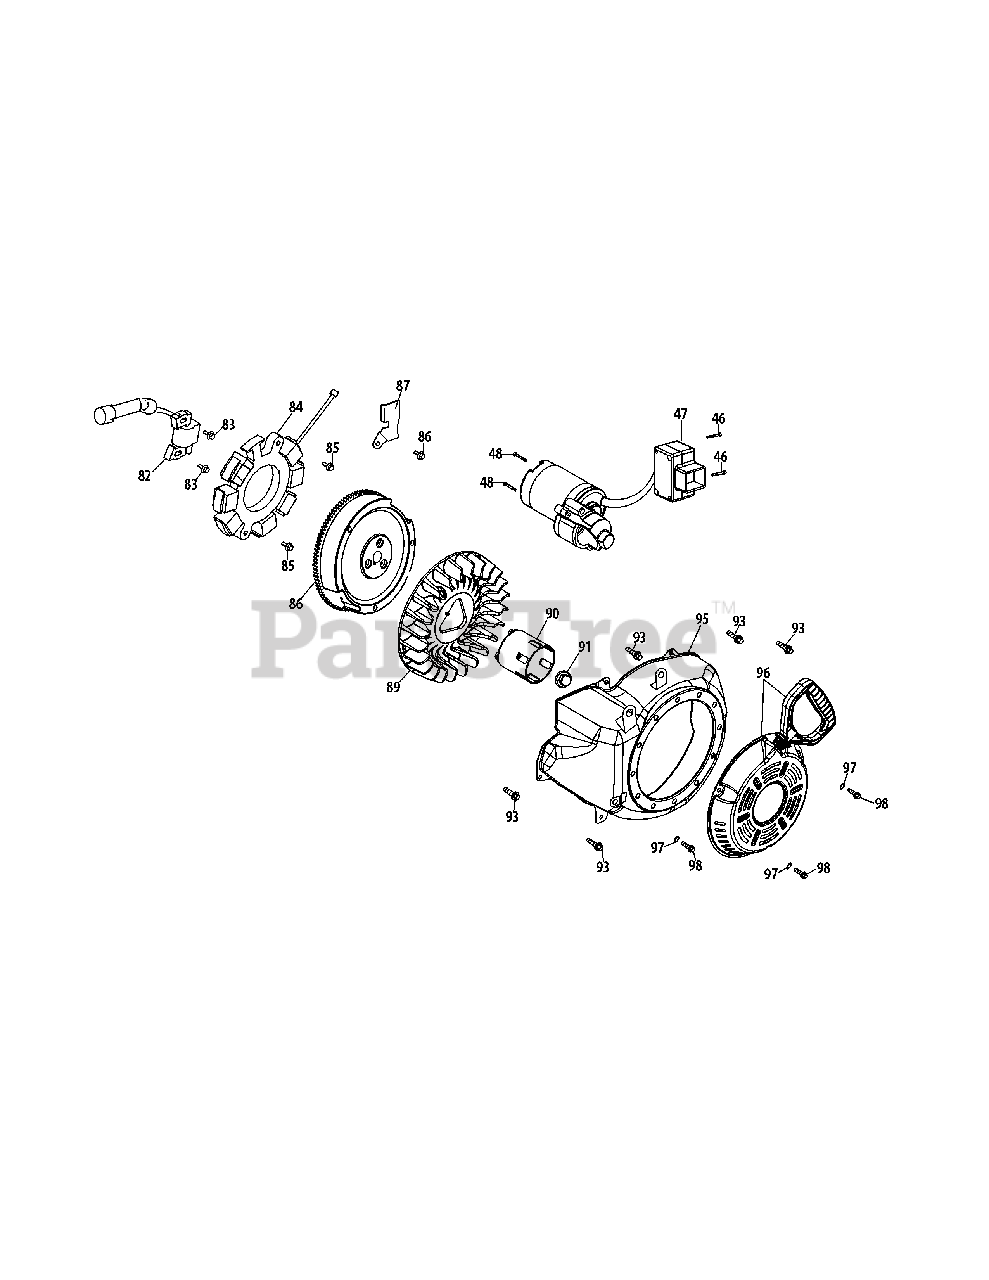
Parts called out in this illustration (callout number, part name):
47	Electric Starter
82	Ignition Coil Assembly
83	Ignition Coil Bolt
84	Coil Assy. Charge
87	Alternator Wire Clamp Brkt
90	Pulley, Starter
91	Nut,Special M16×1.5
95	Blower Housing
96	Recoil Starter
97	Gasket 6
